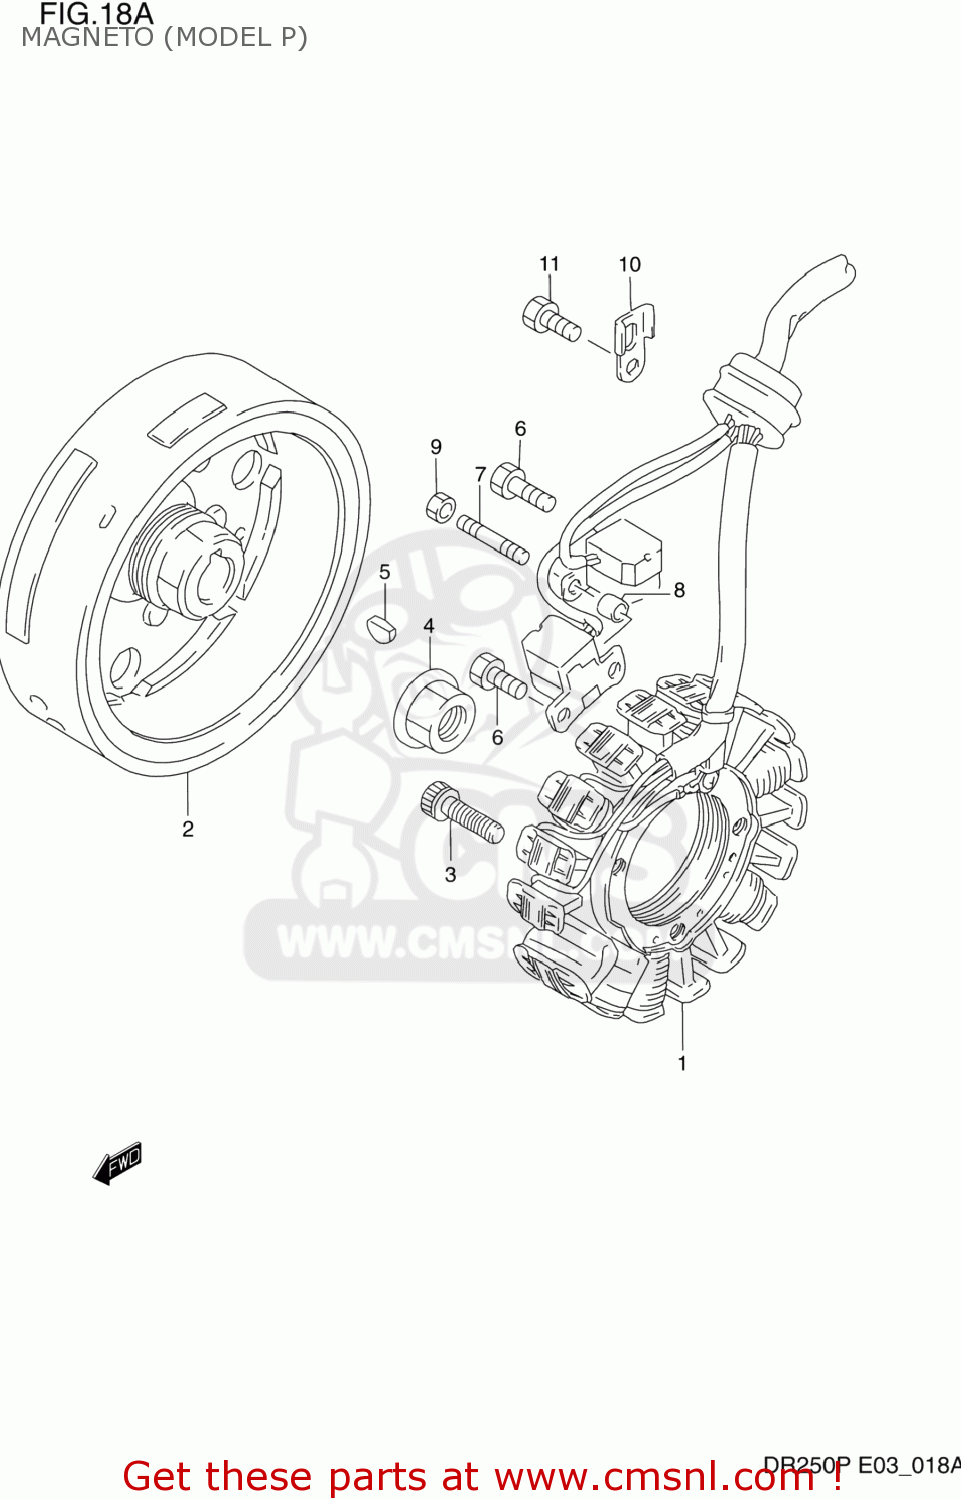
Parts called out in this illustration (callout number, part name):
1	STARTER ASSY
2	ROTOR
3	BOLT
4	NUT
5	KEY
6	BOLT(5X10)
7	BOLT,STUD(5X18)
8	SPACER (5.5X9.5X6.5)
9	NUT 5MM
10	CLAMP,GENERATOR LEAD WIRE
11	BOLT(5X10)
